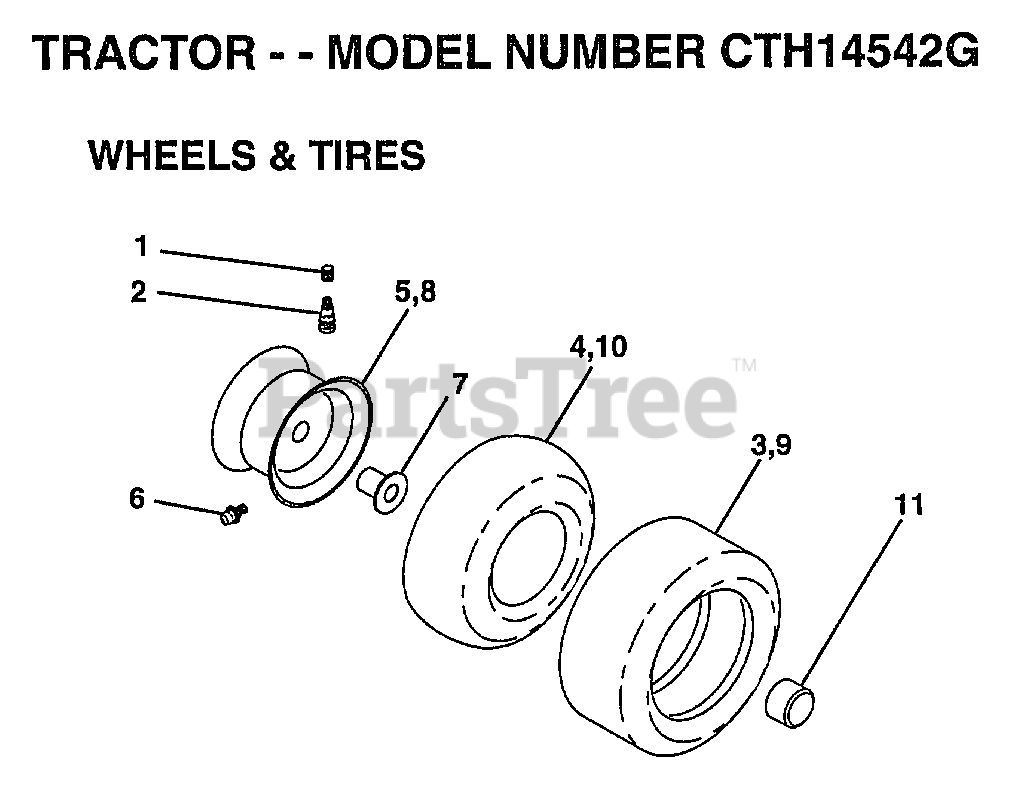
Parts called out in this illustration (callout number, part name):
1	VALVE CAP
2	VALVE STEM LT
4	TUBE.5.3/4.5/6
5	RIM.FRONT.6.YELLO
6	FITTING LT
7	"FLANGE, BEARING"
10	TUBE.18X9.5-8
11	HUB CAP
